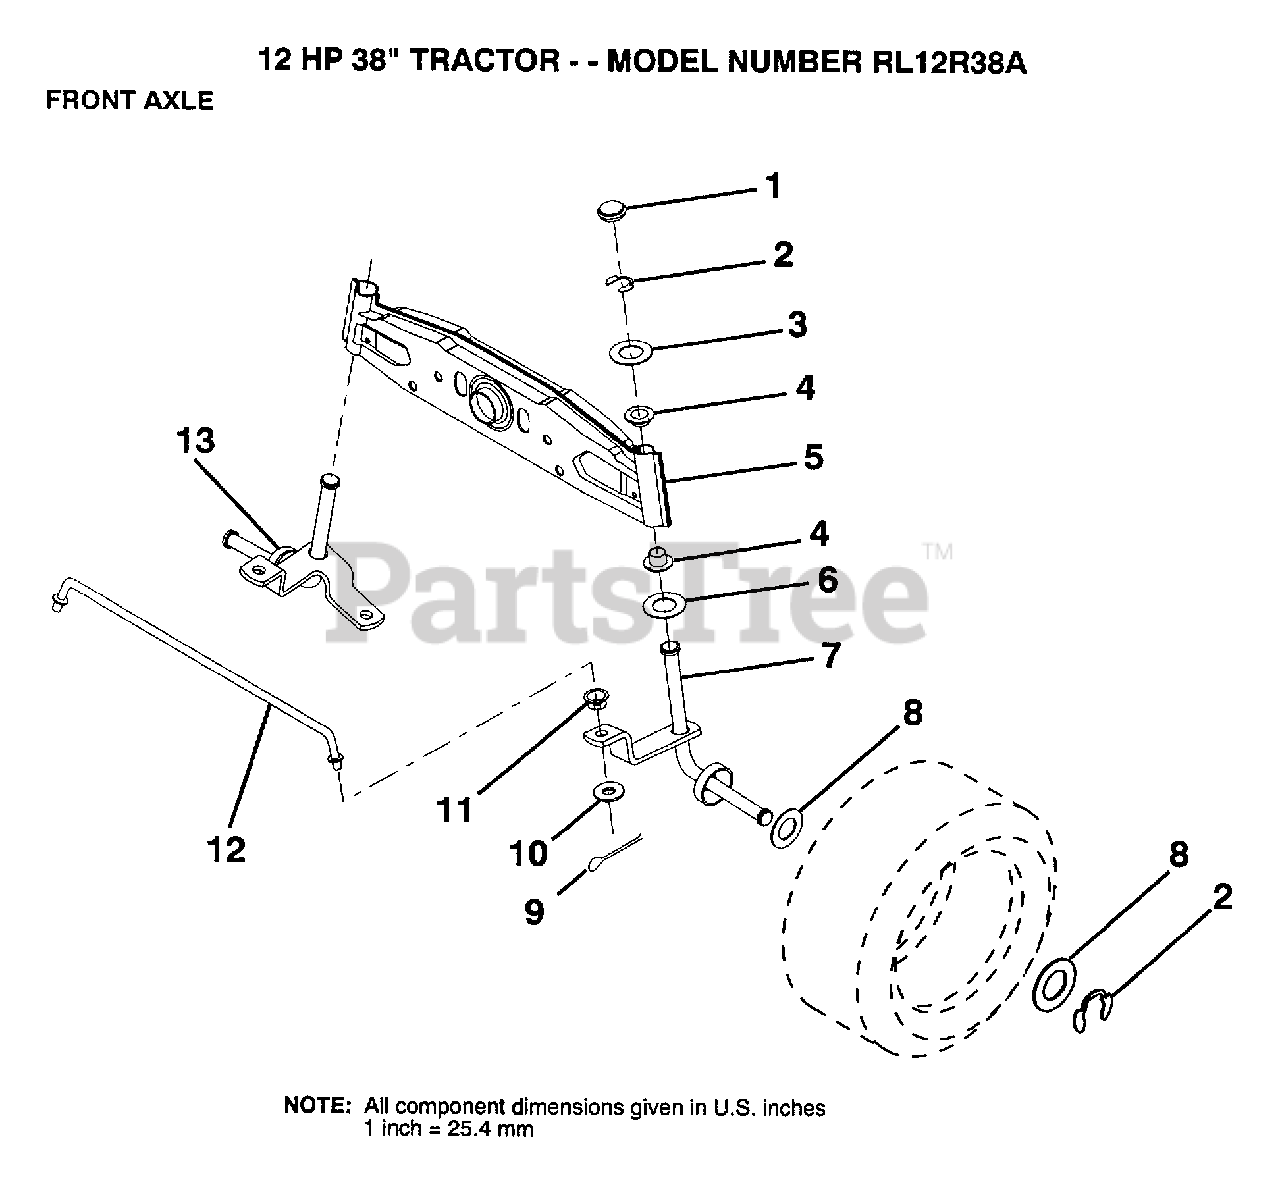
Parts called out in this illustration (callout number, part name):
1	CAP
2	RING
3	WASHER
4	NYLINER
5	AXLE FRONT
6	WASHER .T
7	SPINDLE RH
8	WASHER
9	COTTER PIN
10	WASHER
11	BUSHING.DRAGLINK
12	ROD TIE
13	SPINDLE LH
